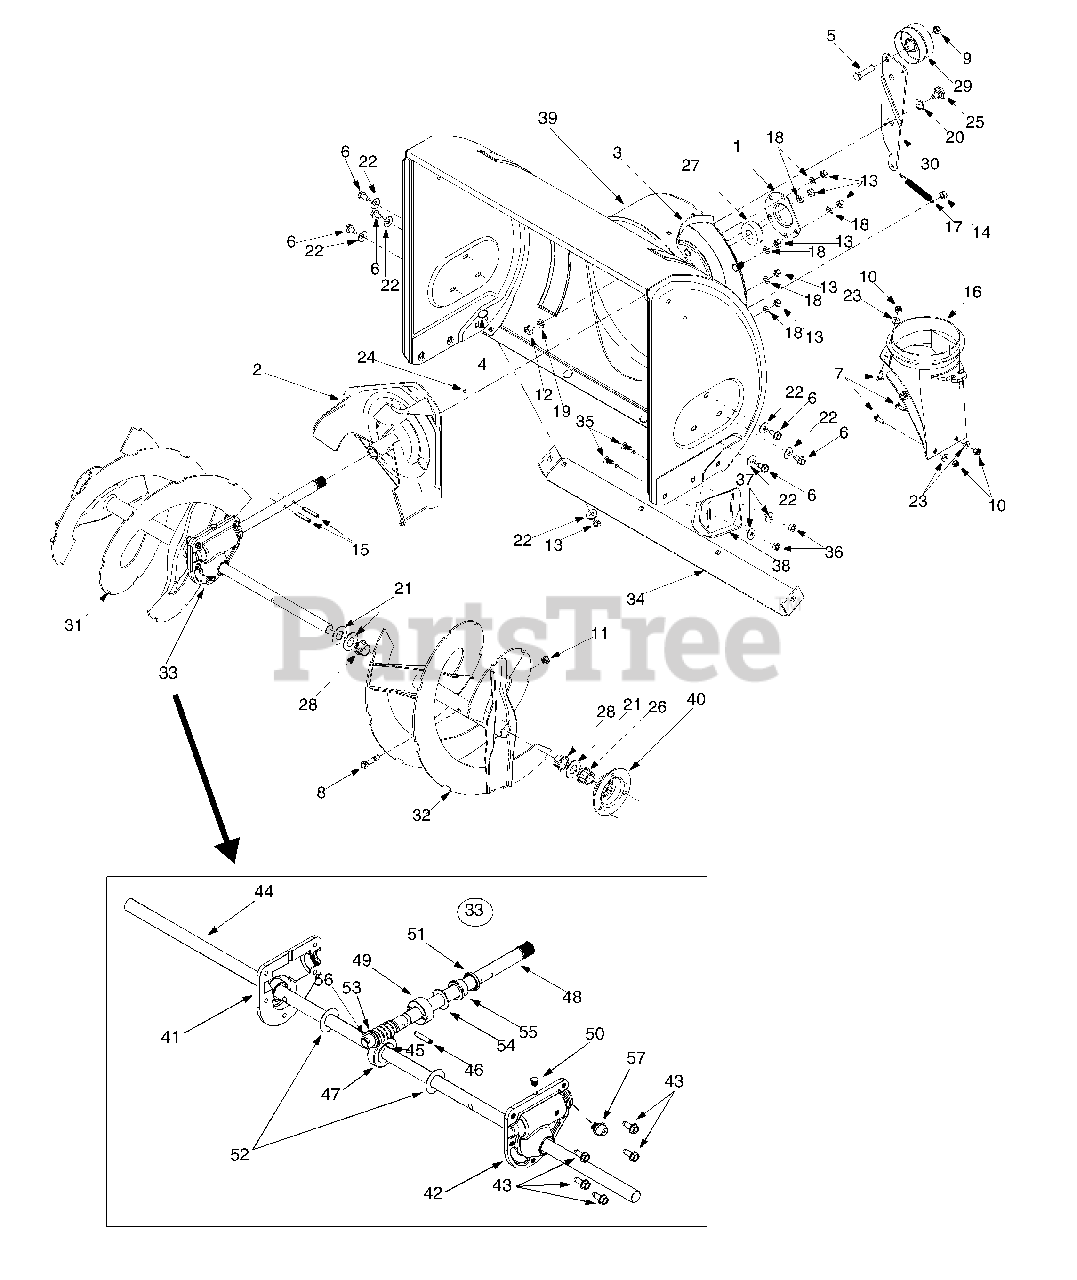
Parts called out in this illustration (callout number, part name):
1	Bearing Housing
4	Carriage Bolt 5/16-18 x .75" Gr.2
5	Hex Screw 3/8-24 x 1.5" Gr.5
6	Hex Washer Head Self-Tapping
7	Carriage Screw 1/4-20 x .75"
8	Shear Bolt 5/16-18 x 1.5"
9	Jam Nut 3/8-24
10	Hex Lock Nut 1/4-20
11	Hex Lock Nut 5/16-18
12	Hex Nut 3/8-16 Gr.2
13	Hex Nut 5/16-18 Gr.5
14	Hex Patch Nut 5/16-18
15	Spiral Pin
16	Chute Adapter
17	Extension Spring
18	Lock Washer
19	Lock Washer
20	Wave Washer
21	Flat Washer
22	Belleville Washer
23	Flat Washer
24	Grease
25	Shoulder Screw
26	Hex Flange Bearing
27	Flange Ball Bearing
28	Flange Bushing
29	Flat Idler
33	Gear Assembly: Auger 28"
35	Carr. Bolt: 5/16-18 x 0.75
36	Hex Nut: 5/16-18 Gr.5
37	Belleville Washer
41	RH Housing
42	LH Housing
43	TT Screw, 1/4-20 x .75
44	Spiral Axle, 28"
45	Hi-Pro Key, 3/16 x 5/8
46	Spring Spiral Pin, .25 x 1.25
47	Worm Gear, 20-tooth
48	Worm Shaft
49	Thrust Collar
50	Grease Plug
51	Grease Seal
52	Flat Washer, .76 x 1.5 x .030
53	Flat Washer, .508 x 1.0 x .020
54	Flat Washer, .76 x 1.5 x .060
55	Flange Bearing, .75 x 1.0 x .59
56	Flange Bearing, .503 ID x 75 OD
57	Grease Fitting
